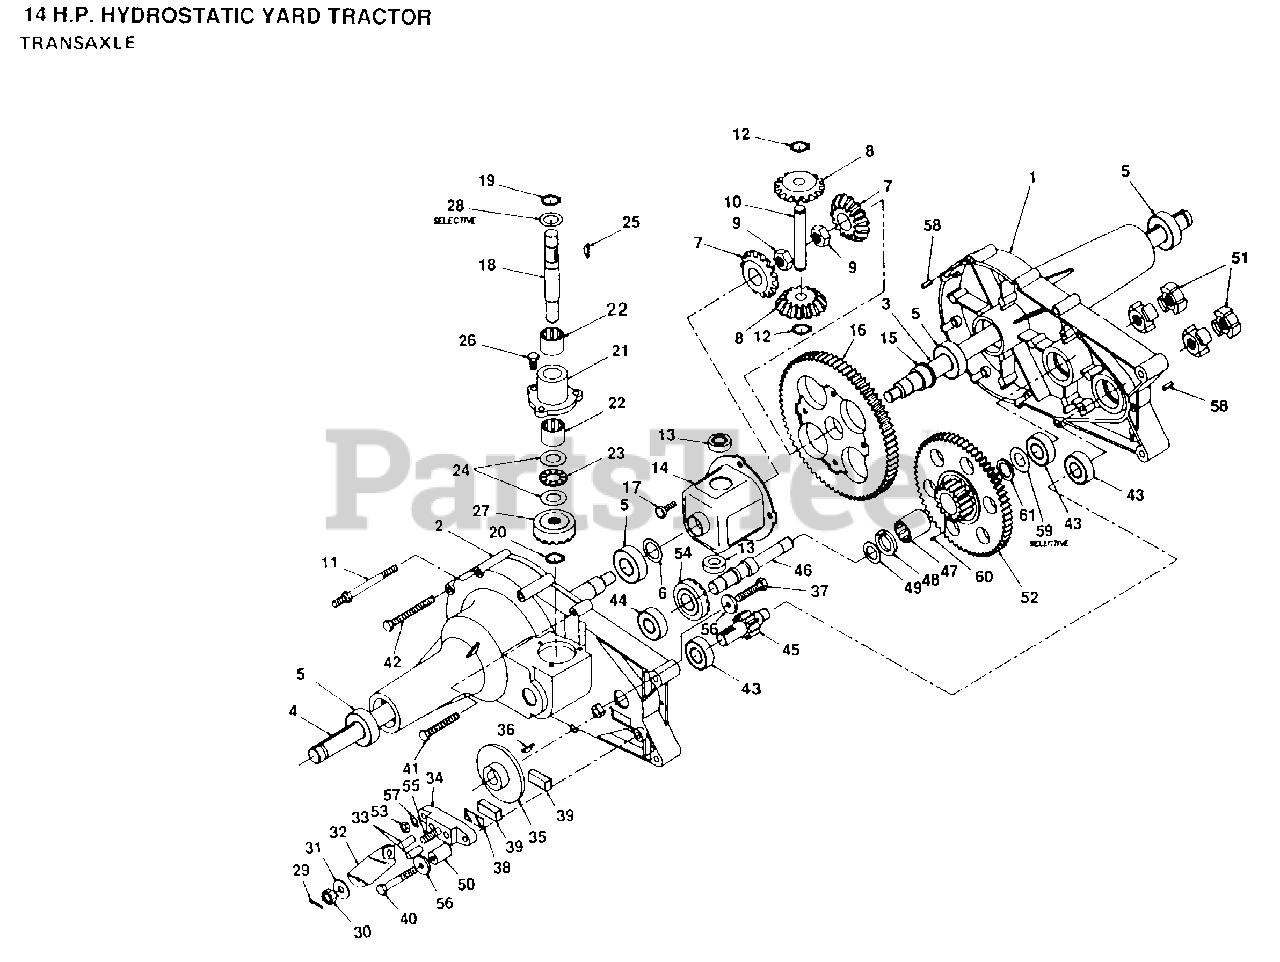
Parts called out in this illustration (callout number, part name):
2	HSG HALF RH-44076
3	AXLE LH -44273
4	AXLE RH-44272
5	BEARING.44121.AGR
6	WASHER -44008
7	GEAR MITER -44096
8	GEAR MITER -44097
9	NUT -44133
10	SHAFT CROSS
11	SCREW-STUD -44271
12	SNAP RING -44146
13	"THRUST, BEARING -44128"
14	HOUSING.ASM.DIFF.-62590
15	"FLANGE, BEARING-44129"
16	GEAR
17	BOLT -44126
18	SHAFT INPUT-44270
19	SNAP RING -44145
20	RET RING (44144)
22	"NEEDLE, BEARING 44099"
23	BEARING.NEE.44139
24	WASHER-44109
25	KEY.44136.HYDRO
26	SCREW
28	WASHER -44125
29	PIN COTTER -44101
30	NUT -44142
31	WASHER FLAT -44130
32	ARM BRAKE 23710
33	PIN BRAKE ACTUATO -44127
34	BRAKE YOKE
35	DISC BRAKE -(44090)
36	KEY -44143
37	SCREW -44277
38	PLATE PUCK -44134
40	SCREW -44300
41	SCREW -44123
42	SCREW -44124
43	"BALL, BEARING -44147"
44	"BALL, BEARING -44232"
45	SHAFT PINION 44083
46	"BALL, BEARING -44147"
47	NEEDLE BEARING -44342
48	THRUST.BRONZE -44343
49	WASHER-44151
50	SPACER -23711
51	COUPLING- 44084
53	NUT -43178
54	PINION-DR.44079
55	BOLT SQ HD
56	WASHER -44278
57	WASHER -44137
58	PIN ROLL-44269
60	DOWEL PIN -44346
61	SEAL GREASE -44394
